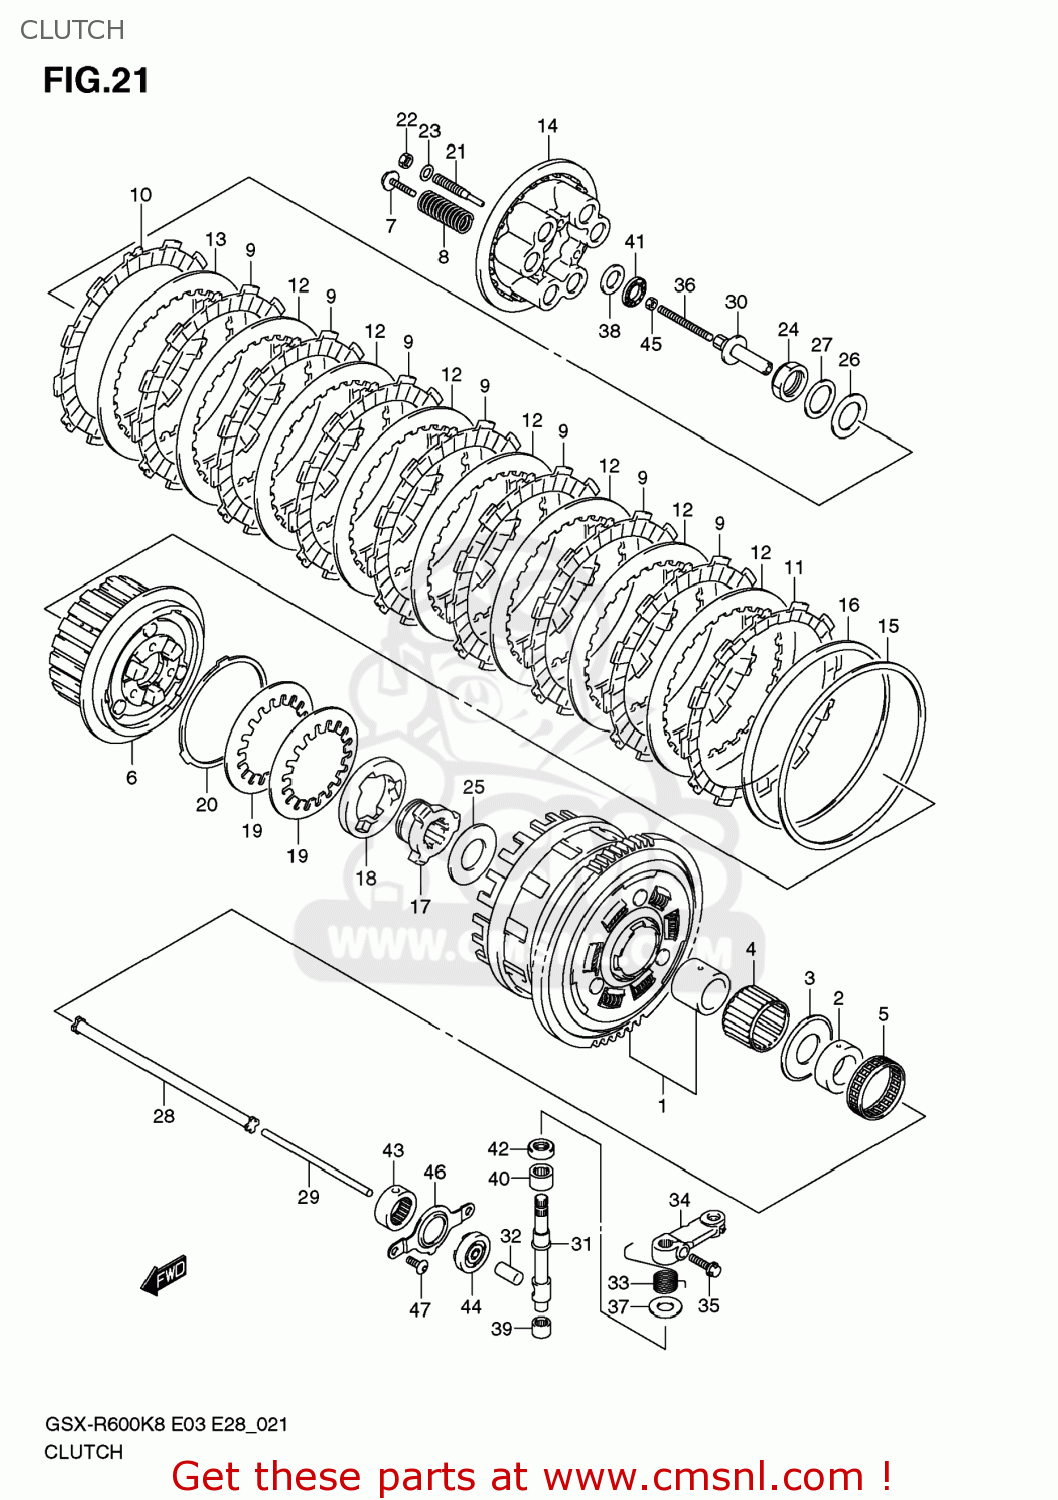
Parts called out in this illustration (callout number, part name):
1	GEAR ASSY,PRI DRIVEN
2	SPACER,OIL PUMP DRIVE SPROCKET
3	WASHER(25X54X2.4)
4	BEARING(35X40X26.8)
5	BEARING(35X40X12)
6	HUB,CLUTCH SLEEVE
7	BOLT,CLUTCH SPRING
8	SPRING,CLUTCH
9	PLATE,CLUTCH DRIVE NO.1 (NAS)
10	PLATE,CLUTCH DRIVE (NAS)
11	PLATE,CLUTCH DRIVE NO.3 (NAS)
12	PLATE,CLUTCH DRIVEN (NAS)
13	PLATE,CLUTCH DRIVEN (NAS)
14	DISC,CLUTCH PRESSURE
15	SEAT,WAVE WASHER
16	WASHER,CLUTCH PLATE WAVE
17	CAM,CLUTCH DRIVE
18	CAM,CLUTCH DRIVEN
19	WASHER,CAM REACTION WAVE
20	WASHER,CAM REACTION SEAT
21	LIFTER,CLUTCH PRESSURE DISC
22	NUT,CL PRESS DISC LIFTER LOCK
23	SHIM(8.8X14X1)
24	NUT
25	WASHER(25X50X2.5)
26	WASHER
27	WASHER(25X41X2.5)
28	ROD,CLUTCH PUSH,R
29	ROD,CLUTCH PUSH,L
30	PIECE,CLUTCH PUSH
31	CAMSHAFT,CLUTCH RELEASE
32	CAP,CLUTCH PUSH ROD
33	SPRING,CLUTCH RELEASE RETURN
34	ARM,CLUTCH REL
35	BOLT(6X20)
36	SCREW(6X73)
37	WASHER(10.5X24X1)
38	WASHER(15.5X28X1)
39	BEARING(10X14X10)
40	BEARING(12X18X12)
41	BEARING(15X28X2)
42	SEAL,OIL(10X20X6)
43	SEAL,OIL(6X34X10)
44	SEAL,OIL(10X17X5)
45	NUT
46	RETAINER,CL PUSH ROD OIL SEAL
47	SCREW(6X13)
